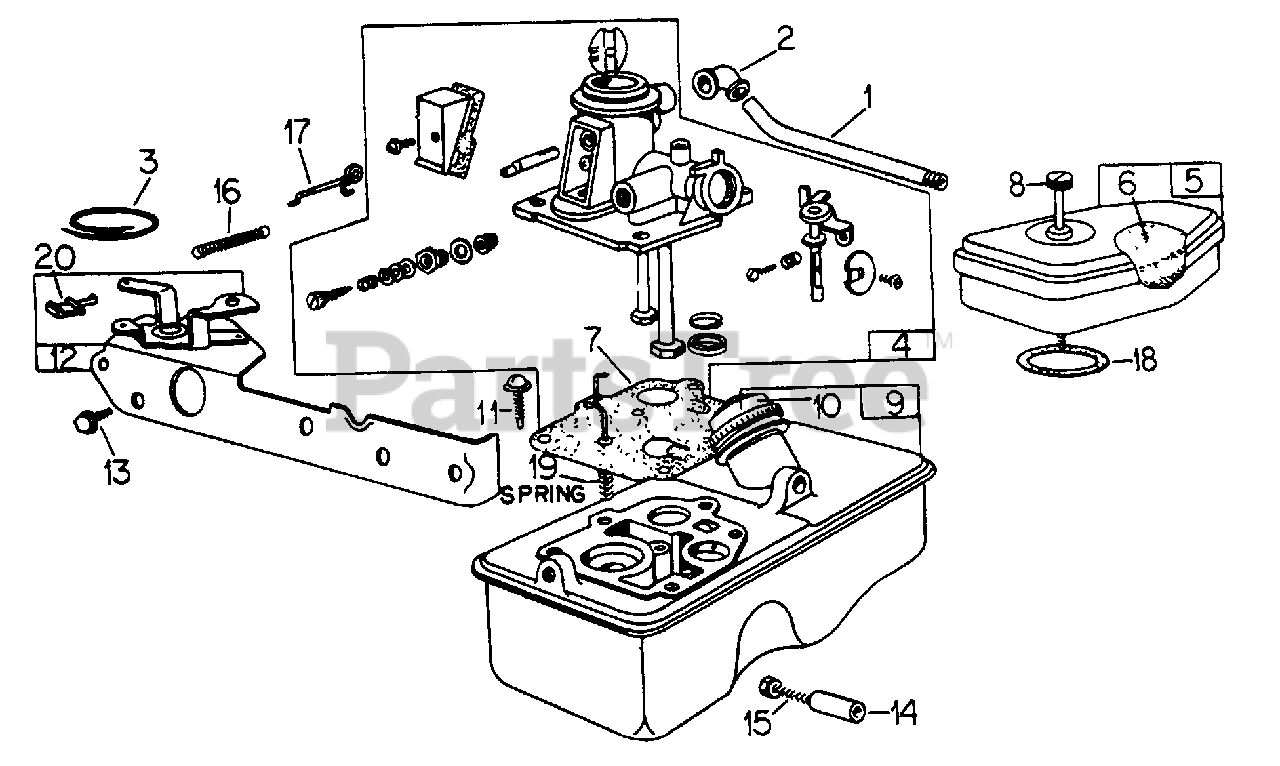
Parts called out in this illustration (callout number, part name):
1	TUBE, BREATHER
2	GROMMET, BREATHER TUBE
3	CABLE, GROUND WIRE
4	CARBURETOR ASSY
5	CLEANER ASSY, AIR
6	ELEMENT, AIR CLEANER
7	DIAPHRAGM, CARBURETOR
8	SCREW, AIR CLEANER
9	TANK ASSY, FUEL
10	CAP, FUEL TANK
11	SCREW, FUEL TANK MOUNTING
12	PLATE, CARBURETOR CONTROL
13	SCREW, CONTROL PLATE TO TANK
14	BUSHING, FUEL TANK SPACER
15	SCREW, FUEL TANK TO STARTER MOTOR
16	SPRING, GOVERNOR
17	SPRING, GOVERNOR LINK
18	GASKET, AIR CLEANER MOUNTING
19	SPRING, DIAPHRAGM
20	SWITCH, STOP
